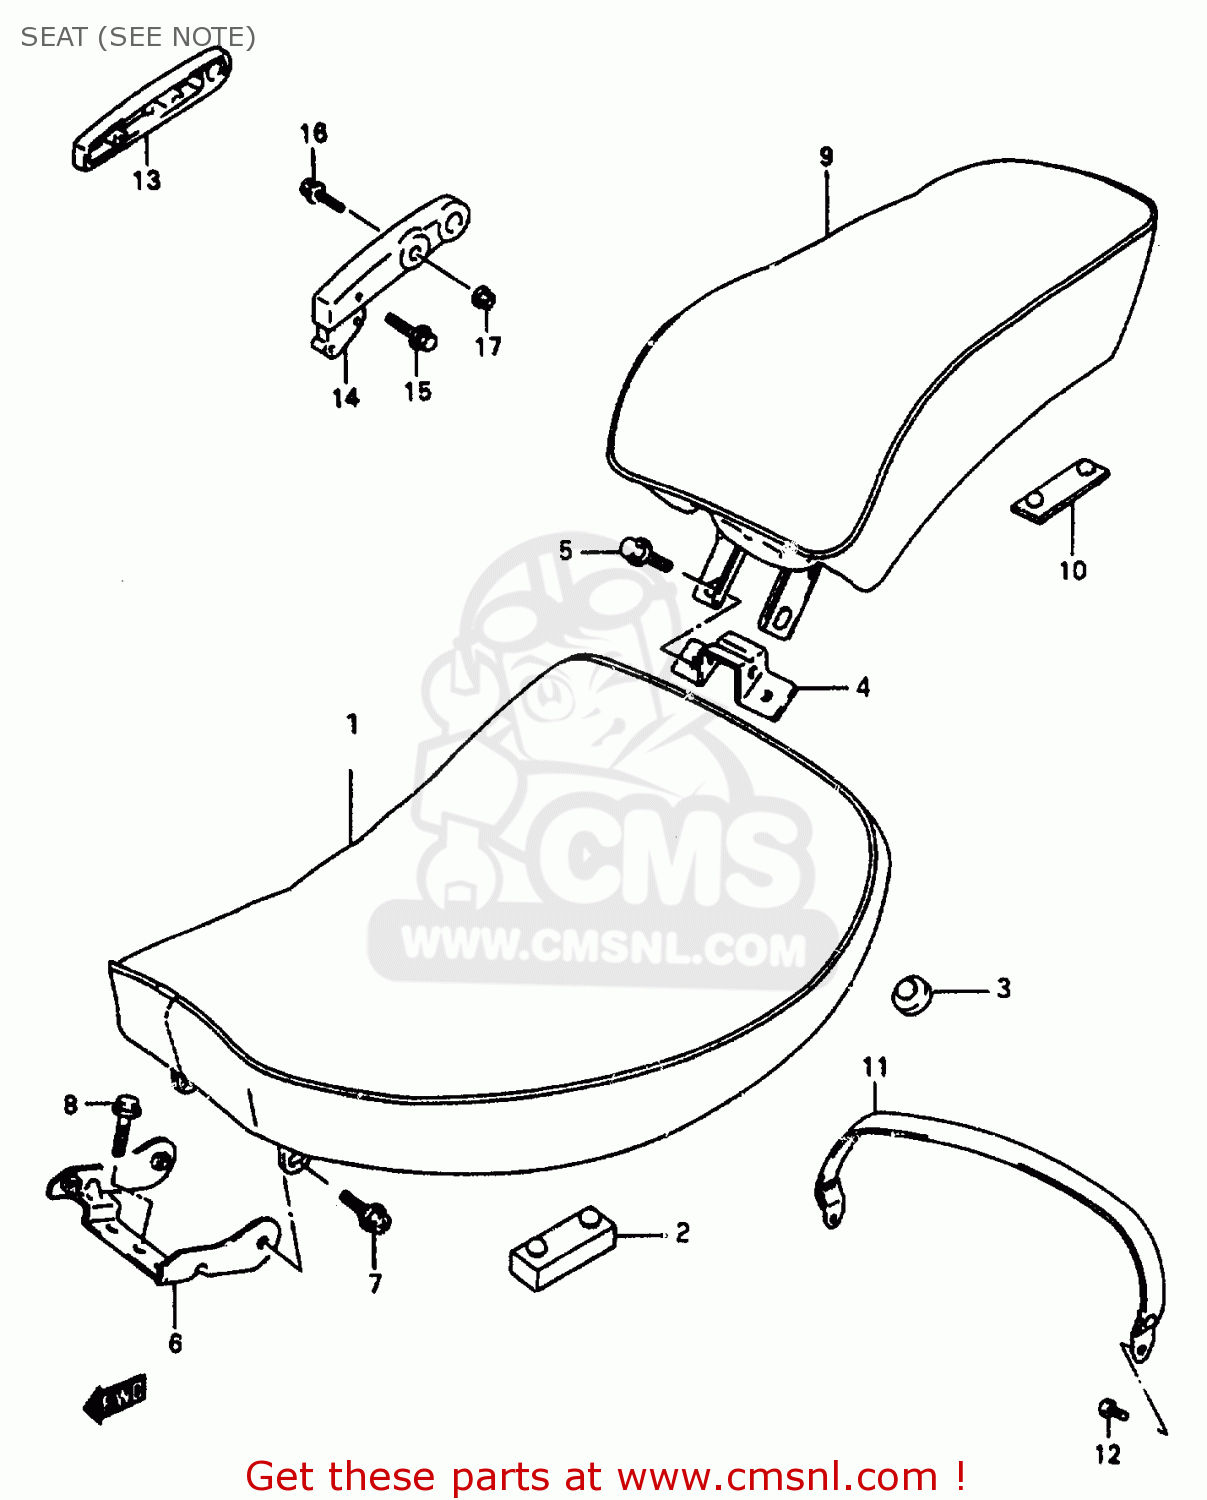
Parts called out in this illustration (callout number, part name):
1	SEAT ASSY
2	CUSHION,SEAT
3	CUSHION
4	PLATE,FR SEAT HOOK & RR
5	BOLT(6X16)
6	BRACKET,SEAT FR
7	BOLT(6X16)
8	BOLT
9	SEAT ASSY,PILLION
10	CUSHION
11	BAND, SEAT
12	BOLT
13	HANDLE,PILLION RIDER,R
14	HANDLE,PILLION RIDER,L
15	BOLT
16	BOLT
17	NUT
18	BOLT
19	BOLT
20	NUT
21	BOLT
22	NUT
